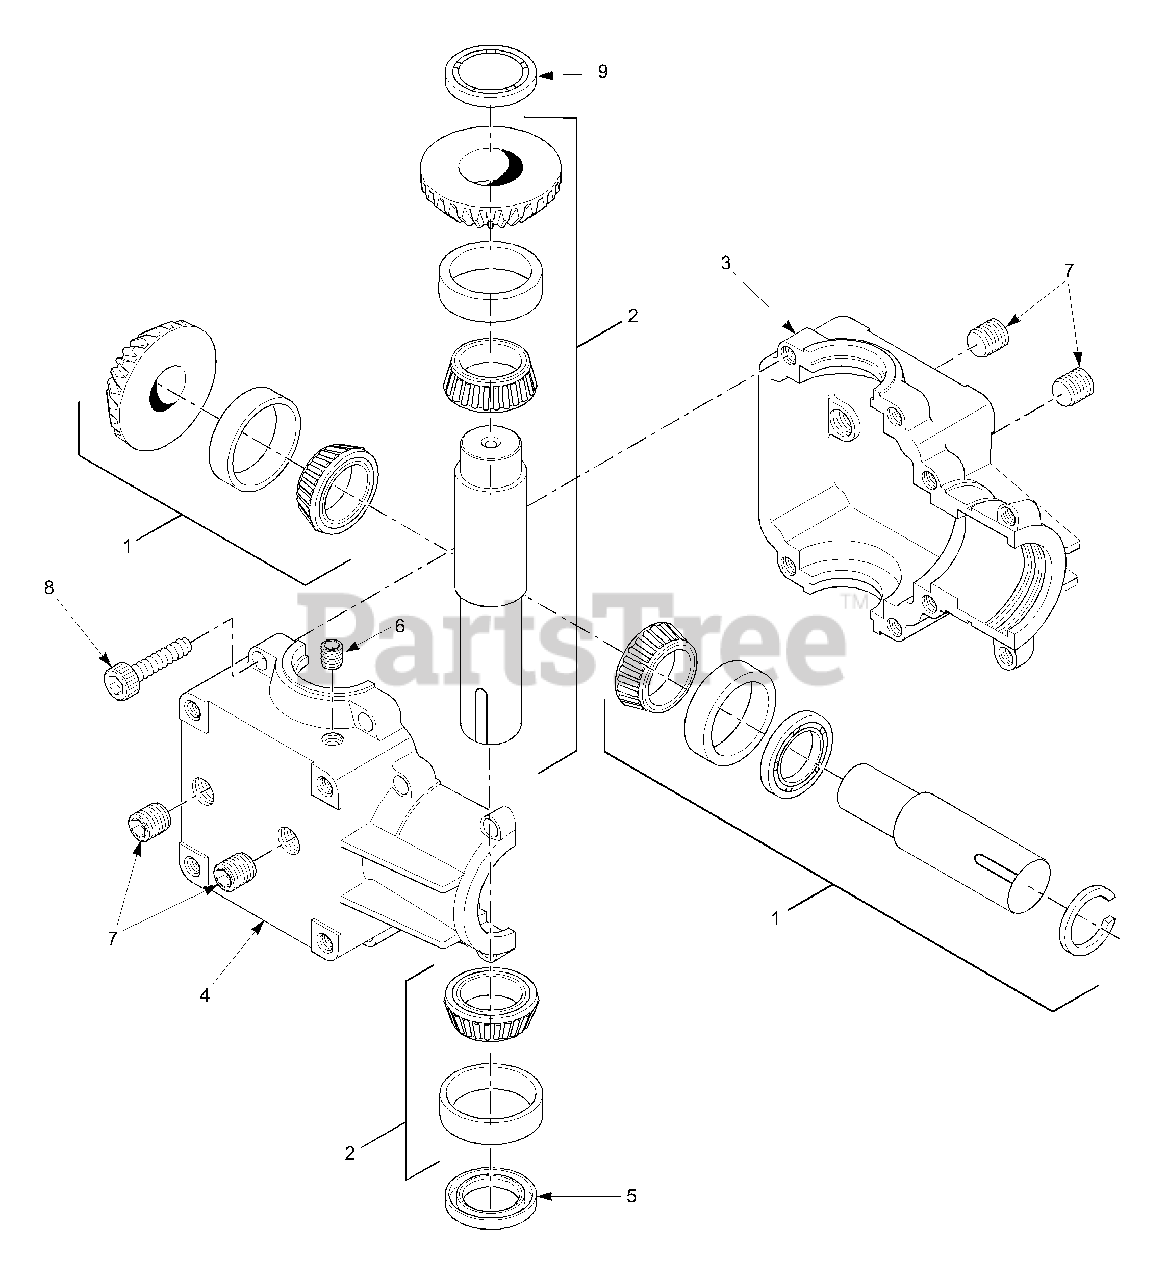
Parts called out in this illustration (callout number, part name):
1	Shaft Assembly
2	Shaft Assembly
3	Case Half
4	Case Half
5	Seal, 1.00" x 1.50" x 3/16"
6	Plug, 1/8" NPT Socket Head
7	Plug, 1/4" NPT Socket Head
8	Bolt, 5/16-18 x 1.25"
